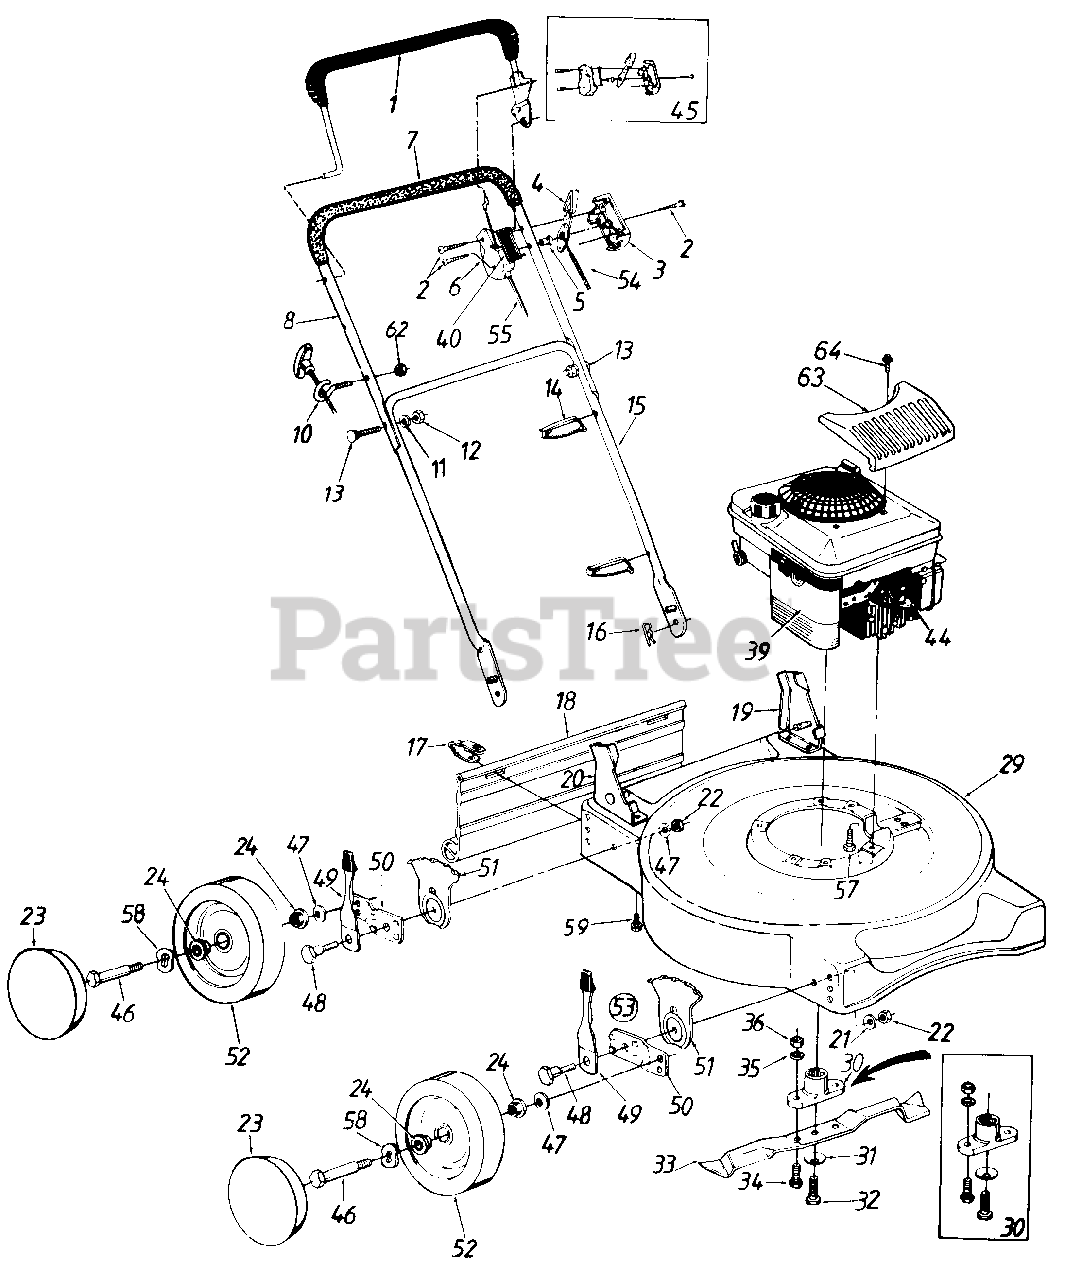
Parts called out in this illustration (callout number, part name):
1	Control Handle Ass'y.
2	Truss Mach. Scr. #12 x 1.5" Lg.
3	Control Panel Half
4	Throttle Control Lever
5	Control Disc Pin
6	Clutch Panel Half
7	Grip
11	L-Wash. 5/16" I.D.
12	1 Hex Nut 5/16-18 Thd.
13	Curved Carriage Bolt 5/16-18 x 1.38" Lg.
14	Cable Tie
15	Lower Handle
16	Hairpin Cotter
17	Hinge Clip
18	Rear Flap
19	Handle Bracket Ass'y.-L.H.
20	Handle Bracket Ass'y.-R.H.
21	Bell-Wash. .39" I.D. x 1.38"
22	Hex Nut 3/8-16 Thd.
23	Hub Cap (Beige)
24	Ball Bearing
29	20" Deck Ass'y.
30	Blade Adapter Kit (Splined)
31	Bell-Wash. .46" I.D.
32	Hex Bolt 7/16-20 x 1.5" Lg.
33	20" Mulching Blade
34	Hex Bolt 3/8-24 x 1" Lg.
35	L-Wash. 3/8" I.D.
36	Hex Nut 3/8-24 Thd.
39	Engine
40	Throttle Label
44	Spark Plug Boot
45	Kit-Control Housing Comp.
47	Bell-Wash. .400" I.D. x .88"
48	Shld. Bolt .50" Dia. x .357"
49	Spring Lever Ass'y. w/Knob
51	Height Adj. Plate
52	Wheel Ass'y. Comp. (Beige)
53	Height Adj. Ass'y. Comp.- 0 R.F. & L.R.
54	Throttle Cable-51"
55	Control Cable-35'
57	Hex L-Wash. Hd. Scr. 3/8-16 x 1.0" Lg.
58	Wave Washer .53" I.D.
59	Hex Wash. Hd. B-Tap Scr. 5/16-18 x .5" Lg.
62	Hex L-Nut 1/4-20 Thd.
63	Engine Cover
64	Truss Hd. Tap Scr. #6 x .6" Lg.
